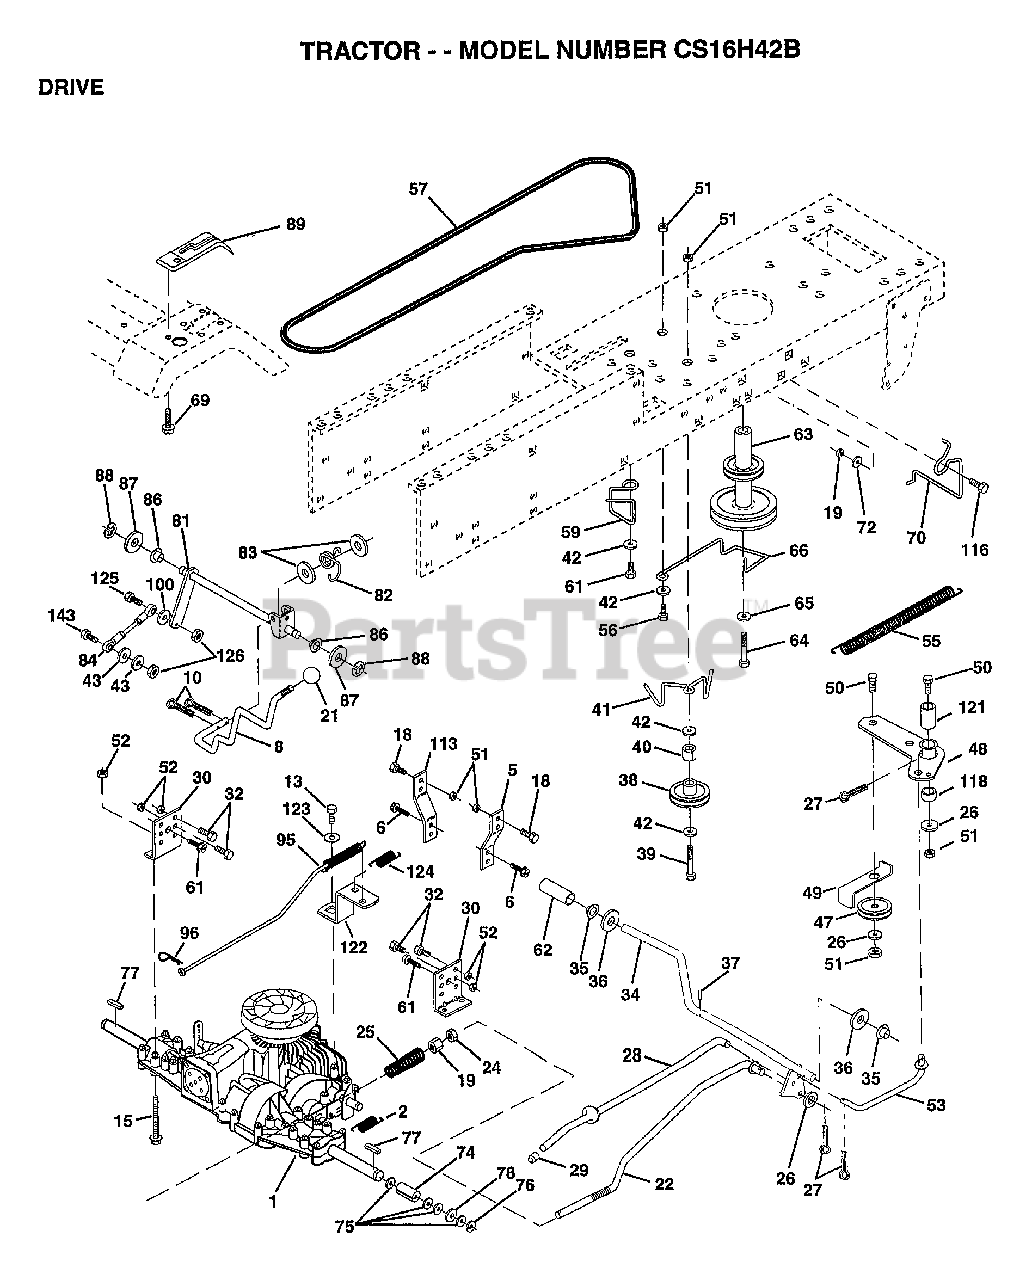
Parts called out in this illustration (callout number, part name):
1	TRANSAXLE, PEERLESS
2	SPRING.BRAKE.RETU
5	STRAP TORQUE
6	SCREW
8	ROD SHIFT FEND LT
10	PIN COTTER 1/8
13	BOLT.1/4-28.W/PAT
15	BOLT.HX.FLG.5/16
18	BOLT
19	NUT
21	KNOB DLX BLK/BLK
22	BRAKE ROD
24	NUT
25	SPRING ROD LT
26	WASHER
27	COTTER PIN
28	ROD.BRAKE.PARK.LT
29	PLUNGER CAP T
30	TRANSAXLE MTG BKT
32	BOLT
34	SHAFT ASM-PEDAL F
35	NYLON BEARING
36	WASHER LT
38	PULLEY.IDLER.FLAT
39	BOLT
40	SPACER T
42	WASHER
43	WASHER T
48	BELLCRANK ASM
49	RETAIN BELT
53	"LINK, CLUTCH T"
55	"SPRING, RETURN LT"
57	"V-BELT,GRD DRIVE"
59	KEEPER BELT CNTSP
61	SCREW
62	PEDAL COVER T
63	PULLEY.ENGINE
64	BOLT
65	LOCKWASHER
66	KEEPER-BELT
69	SCREW HEXWSH H-L
70	KEEPER BELT ENG
72	WASHER 13/32 X 1-1/4 X 12
74	"SPACER AXLE,PVST"
75	WASHER
76	E-RING LT
77	SQUARE KEY
78	WASHER
81	SHAFT ASM CROSS
82	"SPRING,TORSION"
83	WASHER
84	"ROD TIE, PVST 20"""
86	BUSHING
87	WASHER D
88	KLIP RING
95	ROAD ASM BYPASS
96	RETAINER M
100	WASHER M
113	"STRAP,TORQUE"
116	BOLT RDHD 3/8-16
118	SPACER-BELLCRANK
121	NYLINER-CLUTCHING
122	"PLATE-BYPASS,PVST"
123	WASHER
124	SPRING RETURN
143	BOLT
